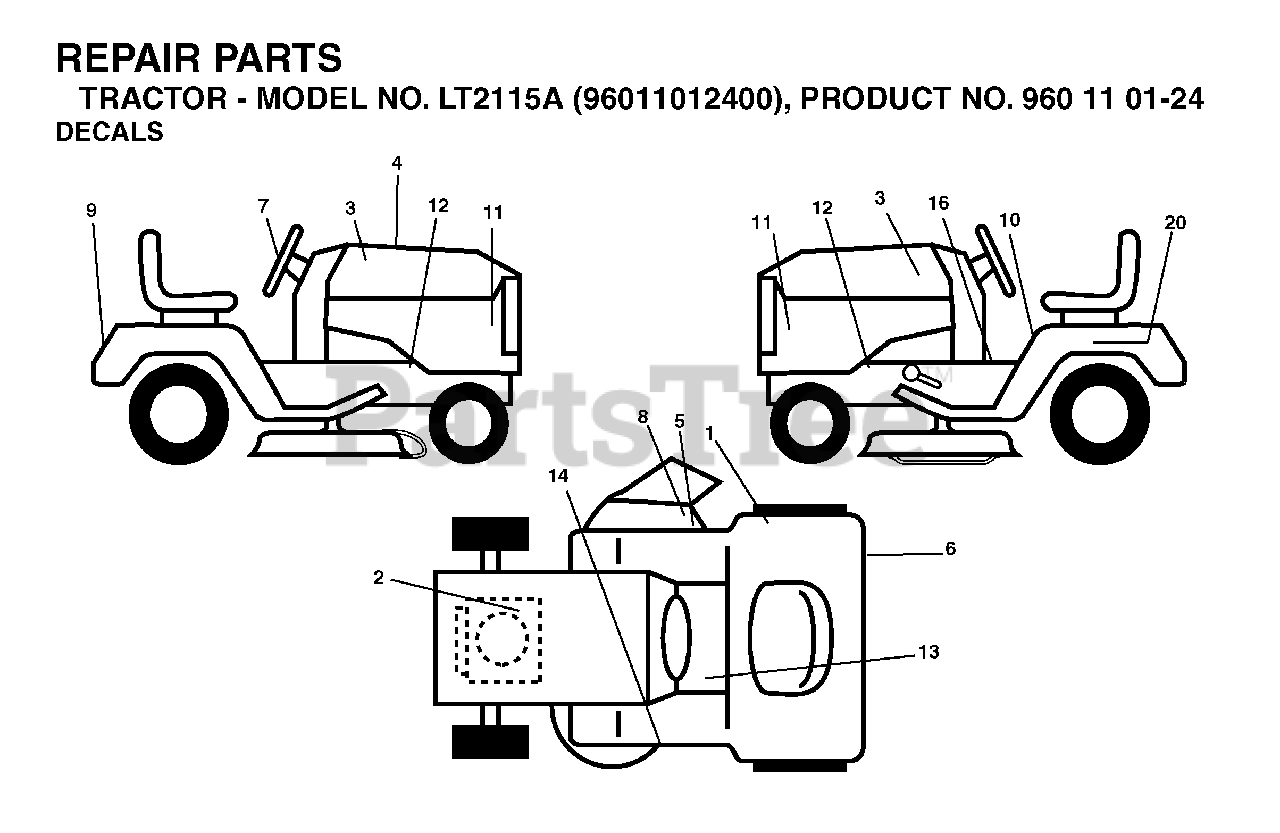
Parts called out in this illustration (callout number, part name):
5	DECAL, DEFLECT WARNING
8	DECAL.INTERNATIONL.CUTFINGER
14	DECAL.V-BELT.SCHEMATIC.36/38/9
16	DECAL PARK BRAKE
20	DECAL BTRY SYMBOLS
